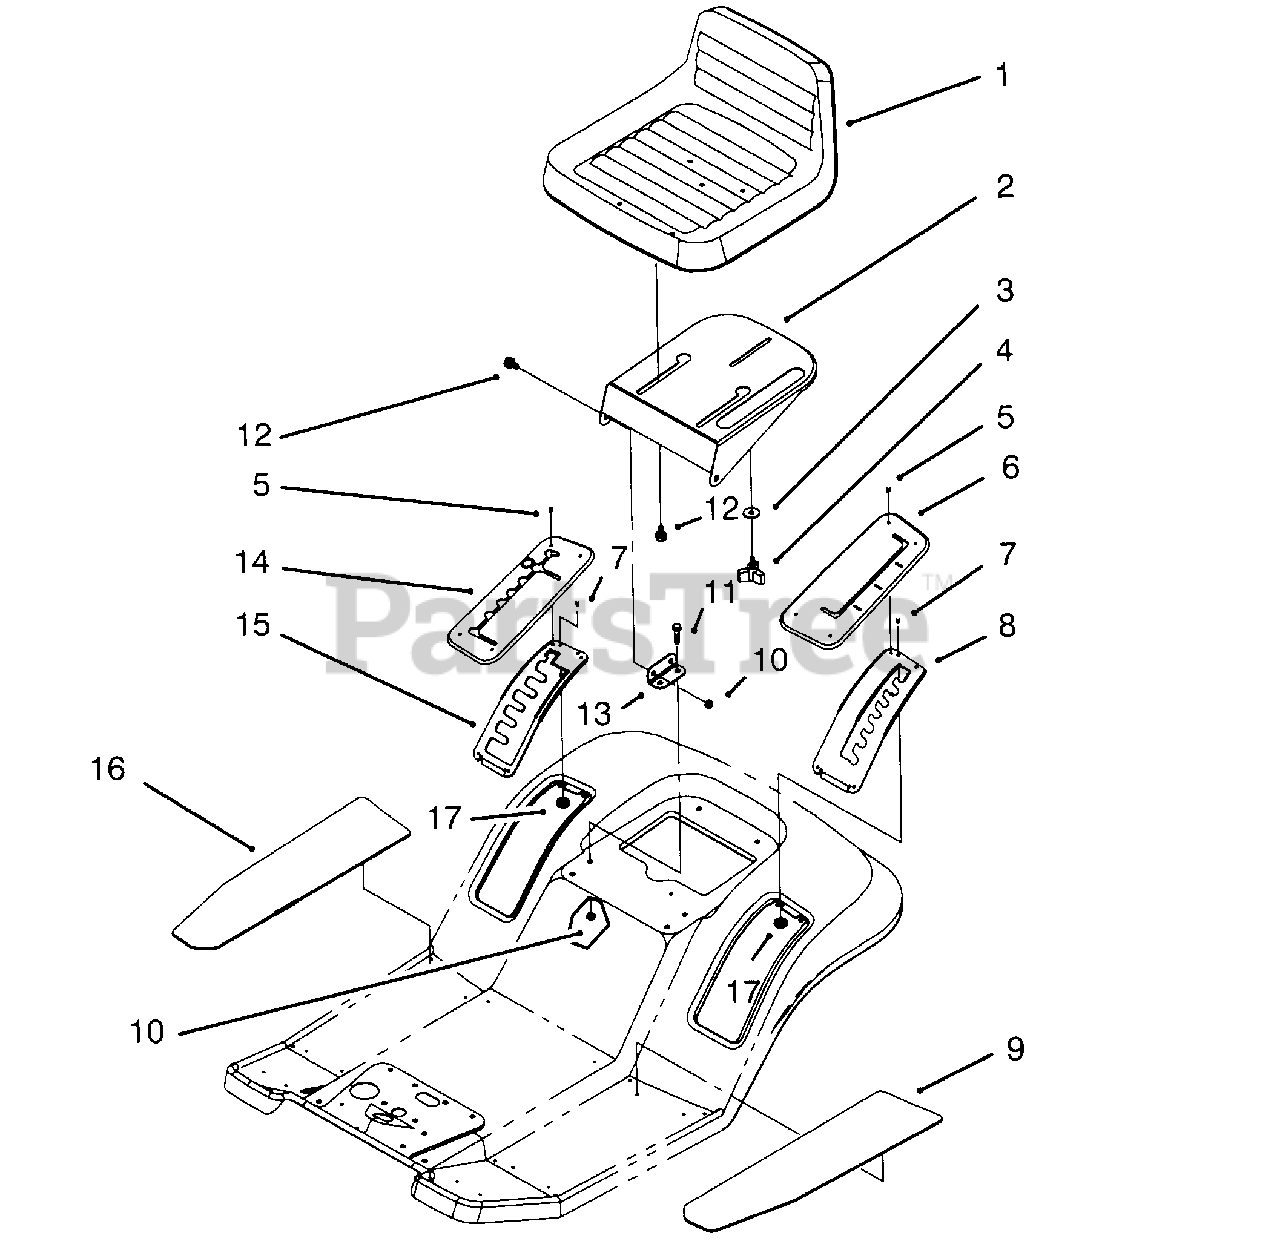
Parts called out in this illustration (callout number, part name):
1	Seat(Model No. 81182 Only)
2	Support-Seat
3	Washer-Fender
4	Knob-Studded
5	Panel-Fastener
6	Cover-H.O.C.
7	Rivet-Pop
8	Gate-H.O.C.
9	Tread-L.H. Foot
10	Nut-Lock
11	Screw-Hex Hd. Cap
12	Bolt-Shoulder
13	Bracket-Seat Hinge
14	Cover-Shift Gate
15	Gate-Shift
16	Tread-R.H. Foot
17	Washer-Backup
